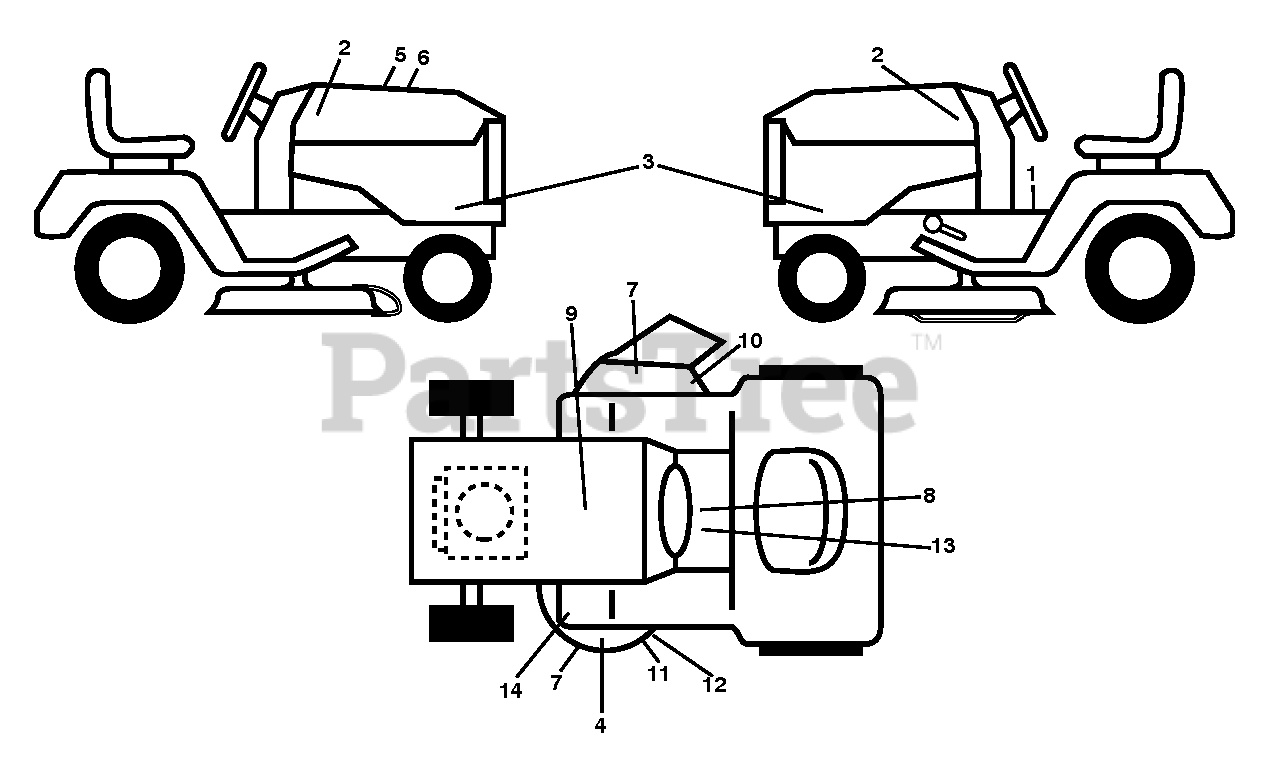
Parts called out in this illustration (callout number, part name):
1	DECAL.FENDER.WARNING
2	DECAL.BADGE.170MM.TEXTLOGO.
3	DECAL.SDPNL.GT2.YT42XLS.SET
4	DECAL.HV.REINFORCED.DECKS.2012
5	DECAL.WARNING.CUST.RESP.E85.
7	DECAL, NO STEP
8	DECAL, WARNING SPARK ARRESTOR
9	DECAL BTRY SYMBOLS
10	DECAL, CAUTION
11	DECAL.MOWER.SCH.48/54
12	DECAL.WARN.KEEP.HAND.AWAY
13	LABEL.EMISS.CALIF.HUSQVARNA
14	DECAL.PEDAL.HUSQ.CROWN
